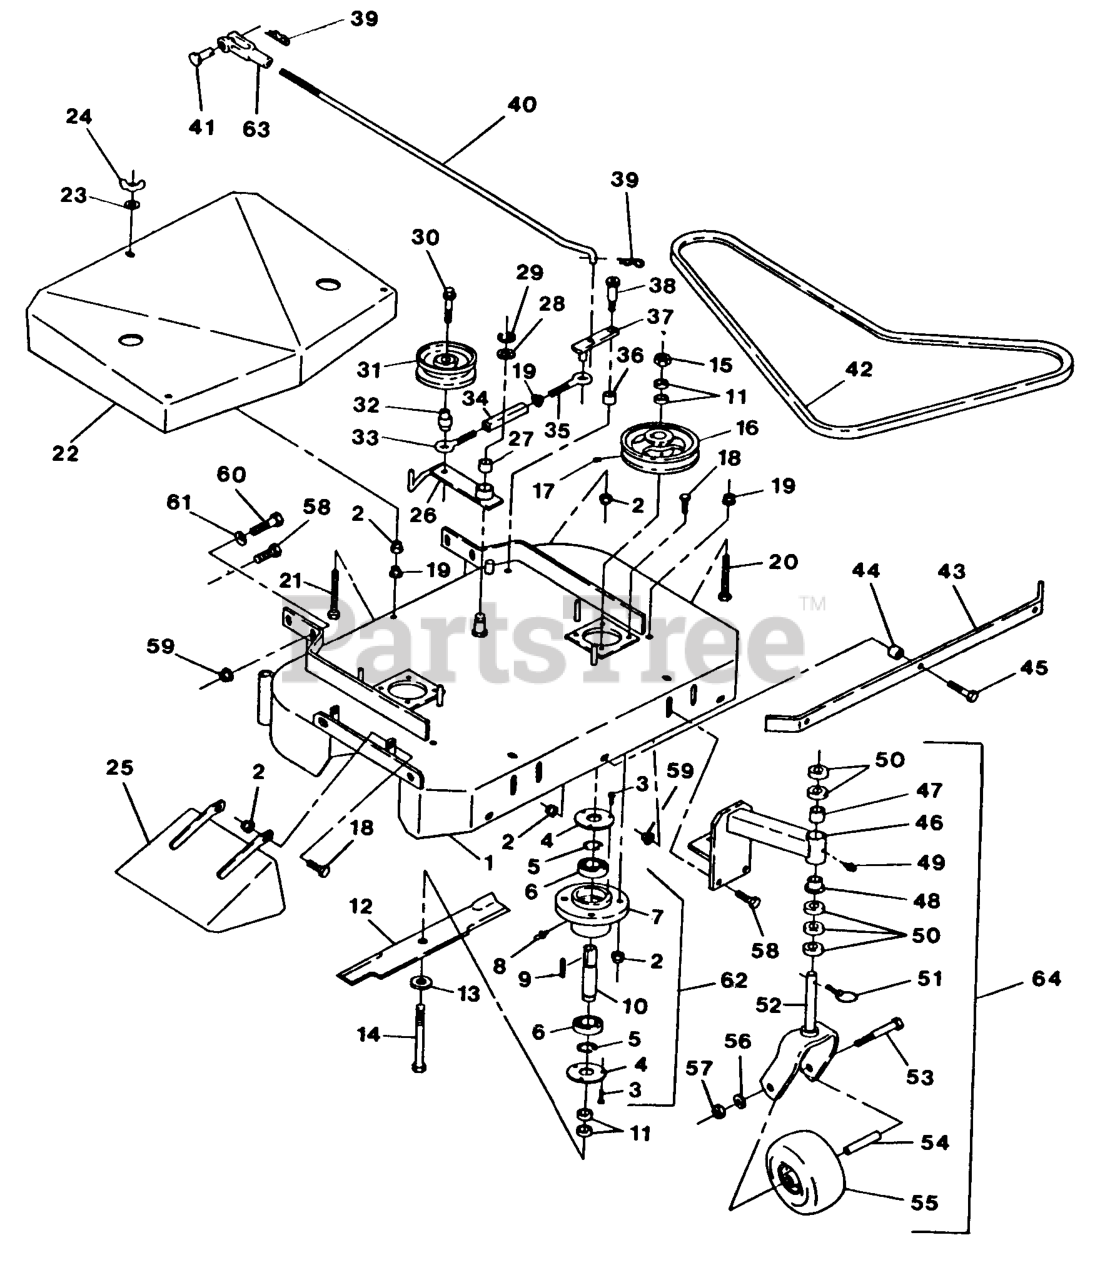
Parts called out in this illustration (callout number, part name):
3	SCRWMACH PHS
7	HOUSING,CUTTER
10	SPINDLE,CUTTER
16	PULLEY,CAST IRON
17	SCREW-SET
20	BOLT,TAP HH
21	BOLTTAP HH
27	BEARING,POWDERED METAL
28	WASHER-SPINDLE
31	IDLER,PULLEY
32	BUSHING-ENGAGEMENT
33	EYEBOLT-THREAD, LH
34	BODY-TURNBUCKLE
35	EYEBOLT-THREAD, RH
38	BOLT,SHLDR KSKH
39	PIN-COTTER
41	PIN-CLEVIS
42	BELT,BLADE DRIVE
47	BEARING,STRAIGHT
50	SPACER-CASTER
62	HOUSING,CUTTER COMPLETE
63	YOKE-ADJUSTABLE
